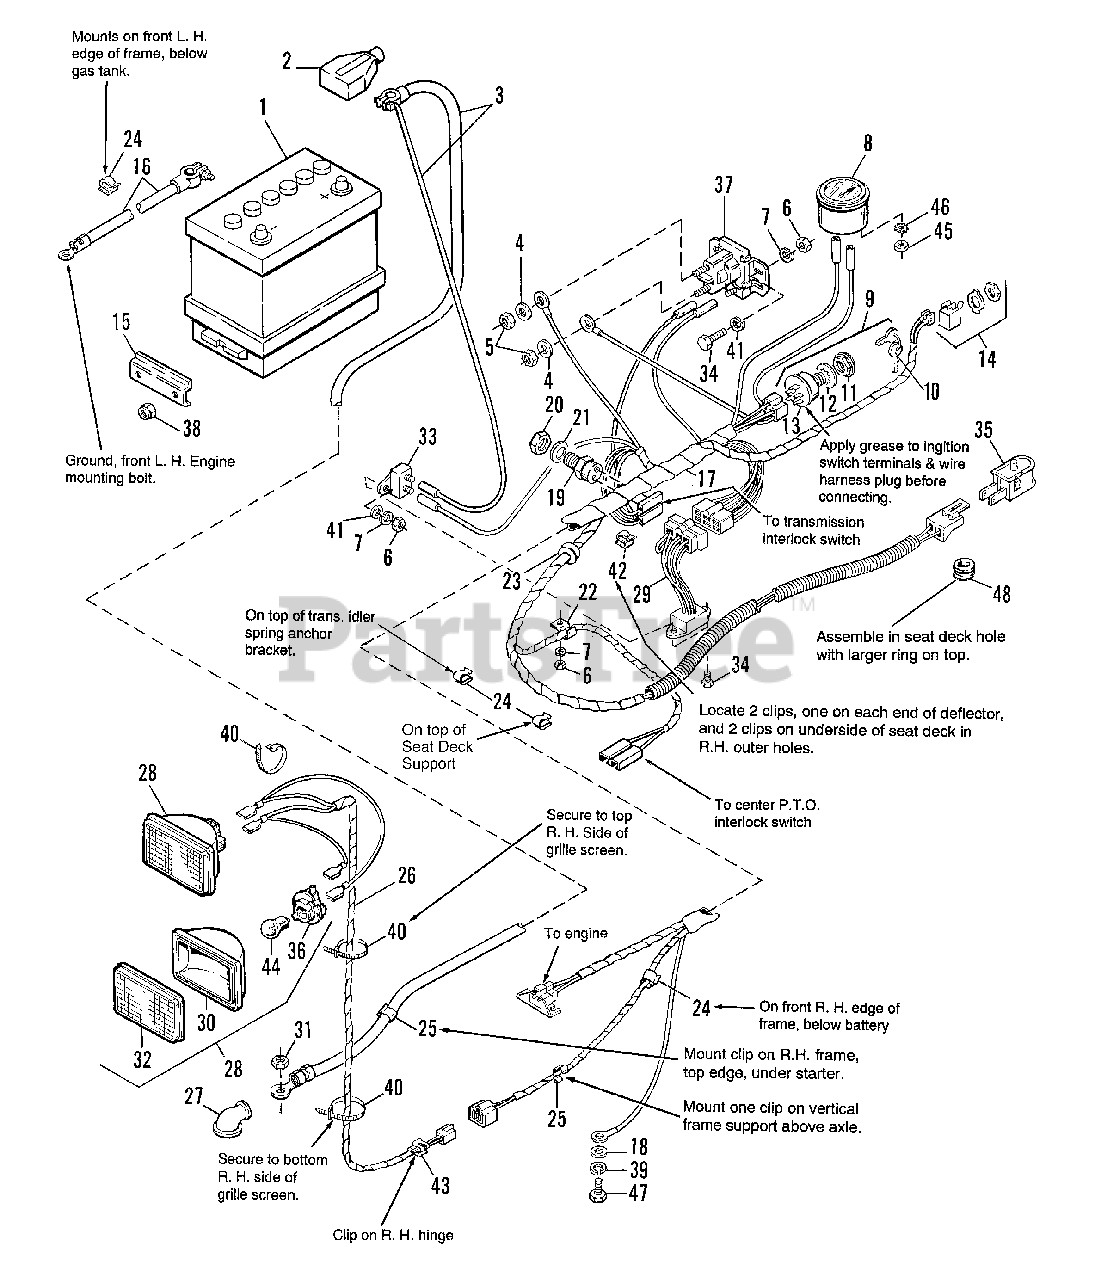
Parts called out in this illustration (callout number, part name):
1	BATTERY,
2	INSULATOR, Battery Terminal
3	CABLE, Battery to Solenoid
4	LOCKWASHER, 5/16
5	NUT, Hex, 5/16-24
6	NUT, Hex, Full, 1/4-20
7	LOCKWASHER, 1/4
9	IGNITION SWITCH KIT
11	NUT, Adapter
12	LOCKWASHER, Int., 5/8
13	SWITCH, Ignition
14	SWITCH, Toggle
16	CABLE (Battery to Ground)
17	HARNESS ASSEMBLY
18	WASHER, 15/32
19	SWITCH, Interlock, Ball
21	WASHER, 9/16
22	CLIP, Cable
23	GROMMET, Rubber
24	CLIP, Tinnerman
25	CLIP, Tinnerman
26	WIRE ASSEMBLY
27	INSULATOR, Terminal Boot
28	HEADLIGHT ASSEMBLY
29	MODULE, Interlock
30	REFLECTOR, Housing
31	NUT, Hex Flange, M8 - 125
32	LENS, Clear
33	BREAKER, Circuit
34	CAPSCREW, Hex Hd, 1/4-20 x 3/4
35	SWITCH, Interlock, Seat
36	SOCKET, Bulb
37	SOLENOID, Starter
38	NUT, Elastic, 5/16-18
39	LOCKWASHER, 7/16
41	WASHER, 1/4
42	CLIP, Wire
43	CLIP, Speed Cable
45	NUT, Hex, #10-32
46	LOCKWASHER, Ext. Tooth
47	CAPSCREW, Hex Hd, 7/16-14 x 1
48	BUSHING, Snap
